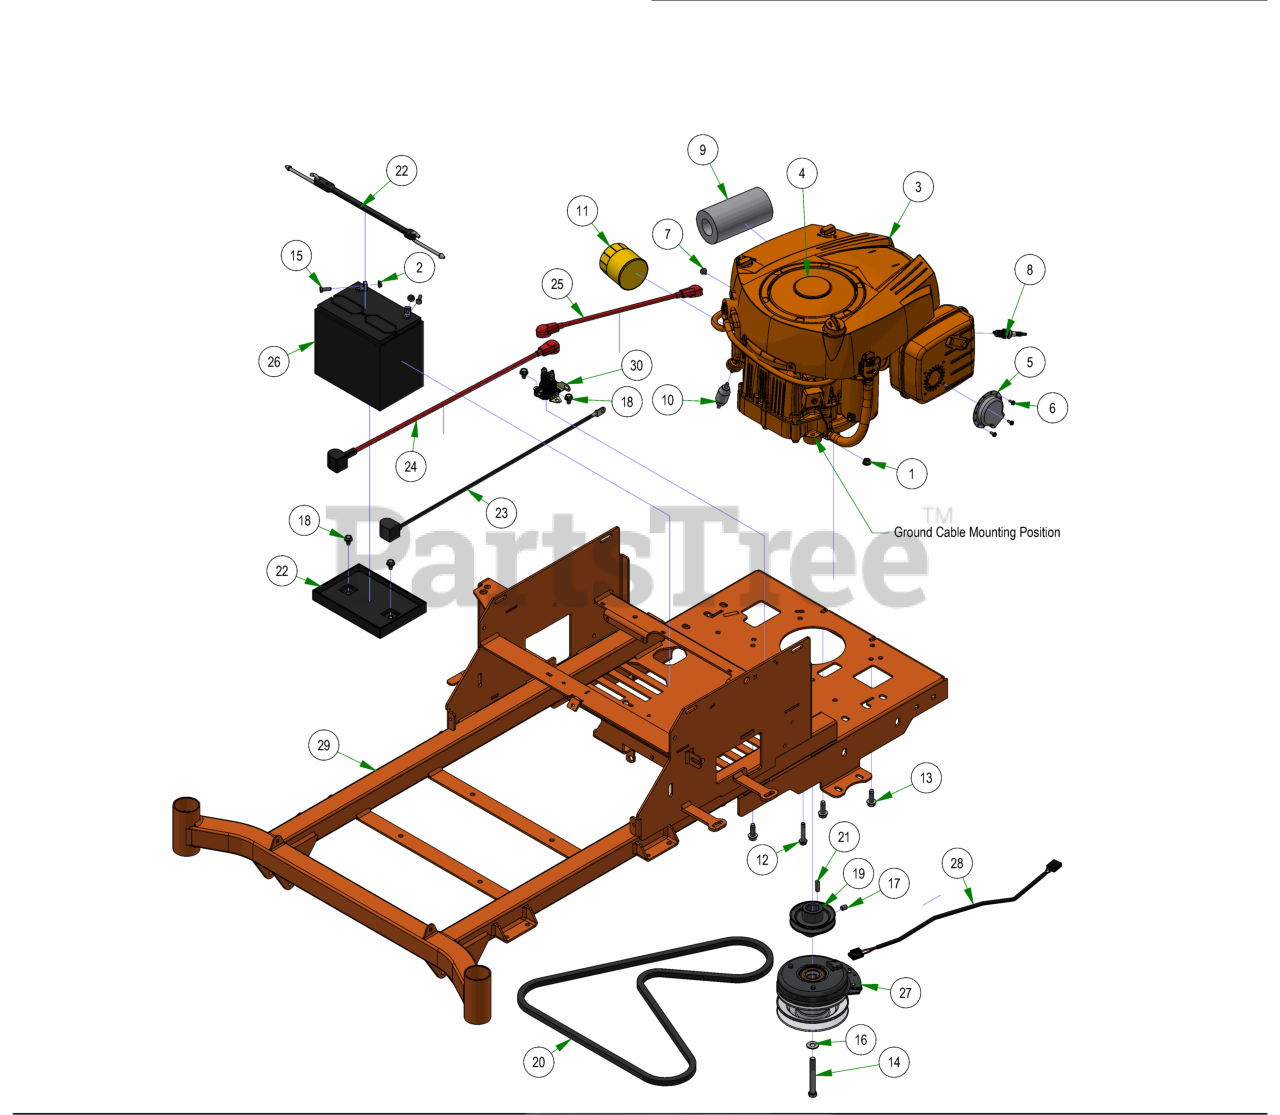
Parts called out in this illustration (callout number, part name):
1	5/16-18 Gr5 Distorted-Thread Flange Locknut
2	1/4-20 HEX SERRATED FLANGE NUT HARD/ZINC
3	19 HP Briggs Engine
4	Briggs 19HP Rotating Screen
5	Muffler Deflector- P/N-222573
6	Muffler Deflector Screws -P/N-96046
7	Choke cable screw/washer- P/N-96073
8	Spark Plug
9	19/21 HP Briggs Air Filter
10	Universal Inline Fuel Filter
11	Oil Filter
12	5/16-18x1-3/4 Gr5 Hex Flange Screw Zinc Clear
13	3/8-16 X 1-1/8 HEX WASHER UNSLOT SERRATED (TRI-LOB) TRS ZINC YELLOW
14	7/16-20 x 3 1/2" Hex Bolt GR8 W/ Patch
15	1/4-20 X 3/4 HEX CAP SCREW (GR.5) ZINC
16	3/8 FLAT WASHER USS (1" OD) ZINC
17	3/8-16 X 1/2 SOCKET SET SCREW (CUP PT) PLAIN
18	5/16-18 X 1/2 HWH unslot (F) tcs zinc
19	3-3/4" Motor Pulley
21	1/4 X 1 SQ MACHINERY KEY 1018 STL PLN
22	2023 Battery Hold Down Assembly
23	24 inch Black Cable – MZ/ZT
24	24" Red Battery Cable
25	14" Red Battery Cable
26	SP-35 Battery
27	105 Ft Lb. Clutch - 1" Shaft
28	Clutch Pigtail
29	2025 MZ 42-48 Frame
